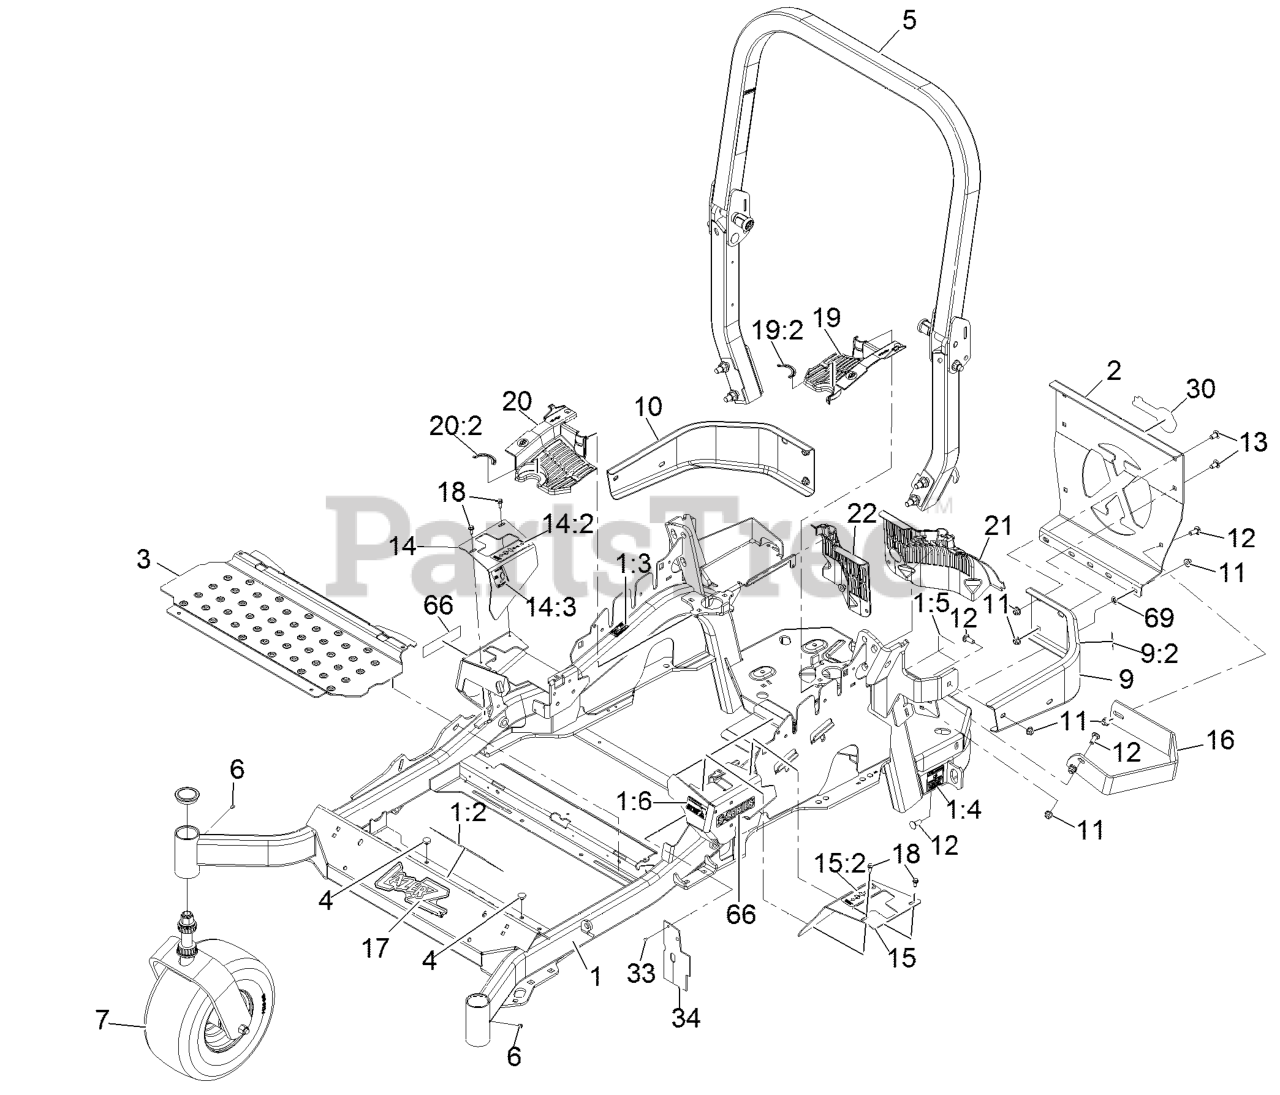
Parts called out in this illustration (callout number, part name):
1	MAINFRAME ASM
1:2	DECAL-CAUTION
1:3	DECAL-SLOPE
1:4	DECAL-BELT DRIVE
1:5	DECAL-SPARK ARRESTER
1:6	DECAL-FUEL FILL
2	PLATE,REAR GUARD
5	ASM,ROPS SERVICE EXMARK
7	Caster Wheel Asm
9	LH BUMPER ASM
9:2	DECAL-CAUTION
10	BUMPER-RH
11	NUT-HF, NI
12	SCREW-CARR
13	SCREW-CARR
14	RH MOTION CONTROL COVER ASM
14:2	DECAL-MOTION CONTROL
14:3	DECAL-PARK BRAKE
15	LH MOTION CONTROL COVER ASM
15:2	DECAL-MOTION CONTROL
17	DECAL,LAZER MODEL
18	SCREW-HWH
19	LH HYDRO GUARD ASM
19:2	DECAL-HYDRO OIL
20	RH HYDRO GUARD ASM
20:2	DECAL-HYDRO OIL
21	GUARD-HYDRO, REAR (LH)
22	GUARD-HYDRO, REAR (RH)
33	RIVET-POP
34	DEFLECTOR-AIR FLOW
66	DECAL-S-SERIES
69	NUT-PUSH
